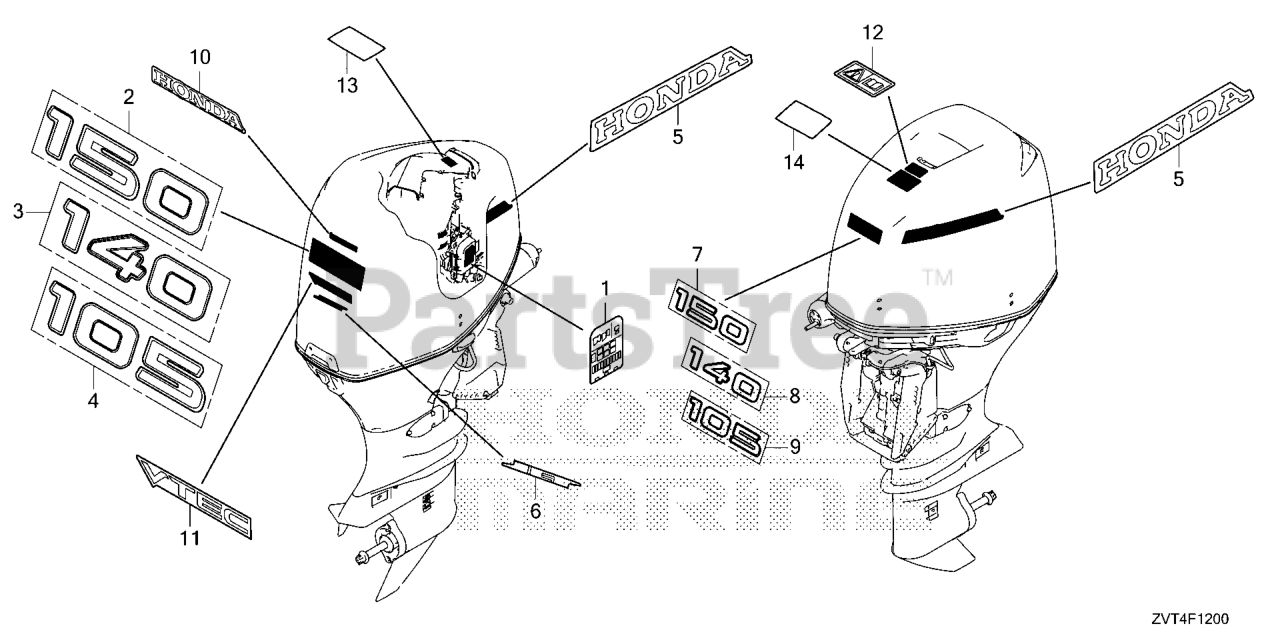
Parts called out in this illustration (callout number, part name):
1	LABEL, FUSE
3	MARK, RR. (140)
5	MARK, SI (STRIPE150)
8	MARK, FR. (140)
10	MARK, HONDA
11	MARK (VTEC)
13	LABEL, CAUTION OIL
14	LABEL, WARNING OPERATOR (ENGLISH)
